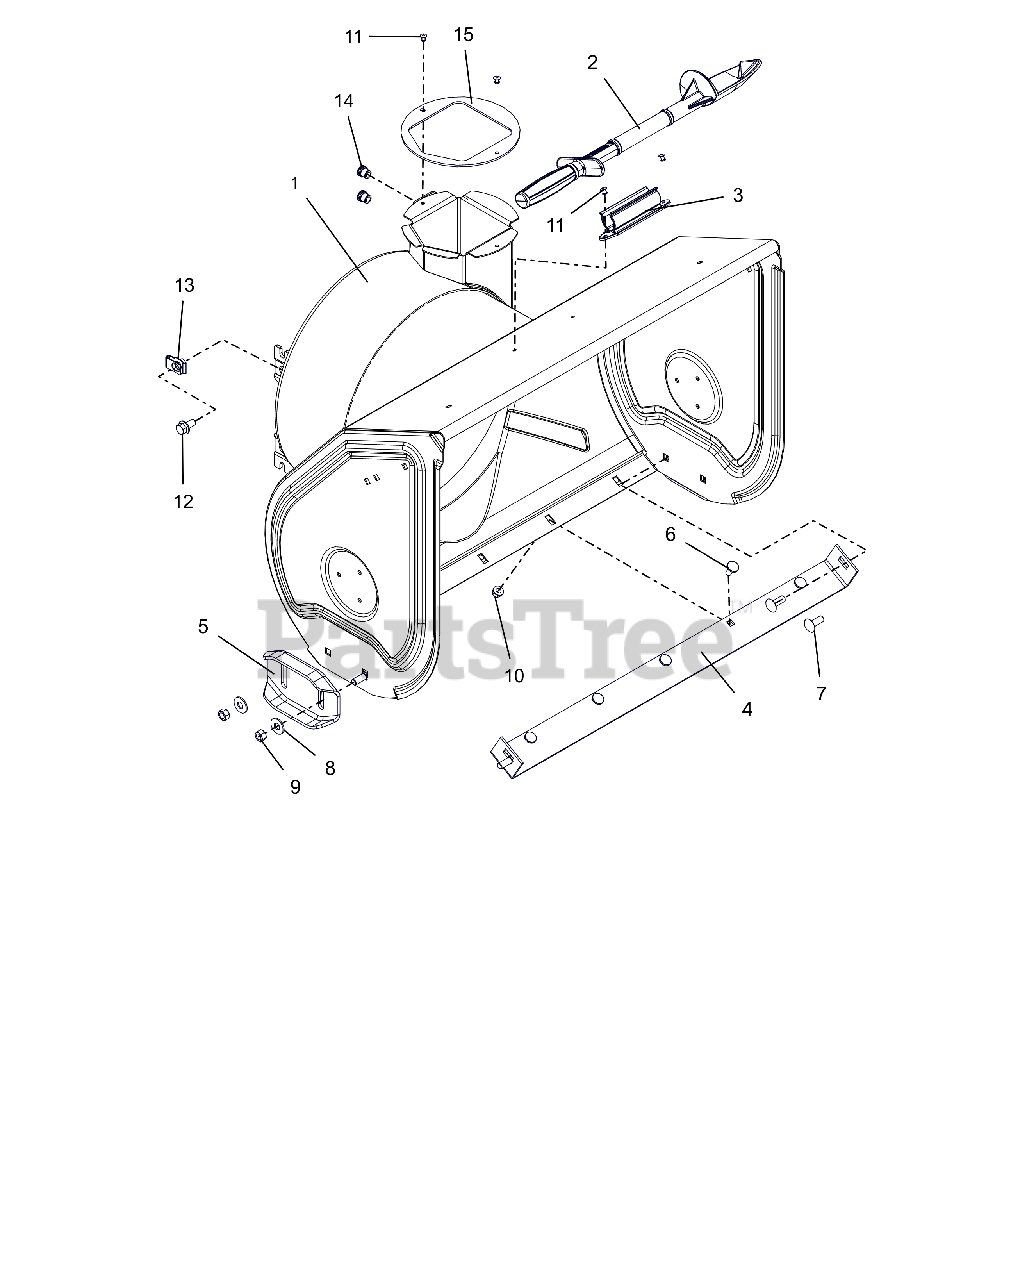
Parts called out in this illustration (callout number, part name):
1	BLOWER HOUSING W/DECAL 28"
2	DEVICE, SNOW CLEAN OUT
3	MOUNT, SNOW CLEAN OUT
4	BLADE, SCRAPER - 28"
5	SKID SHOE, REVERSIBLE - ORANGE
6	BOLT, MODIFIED HEAD CARRIAGE
7	BLT,RHSSN .38-16X1.00 G5 ZCC
8	WSHR,FLT .438X1.00X.083 ZCC
9	NUT-LK-CTR .38-16 ZC120
10	NUT-LK-TOP-FLG .312-18 GF ZCC
11	RVT, POP .1875 ZCC
13	NUT-RTNR .375-16X.37
14	NUT,THD,INSERT .38-16 ZC120
15	BAFFLE, DISCHARGE NECK
